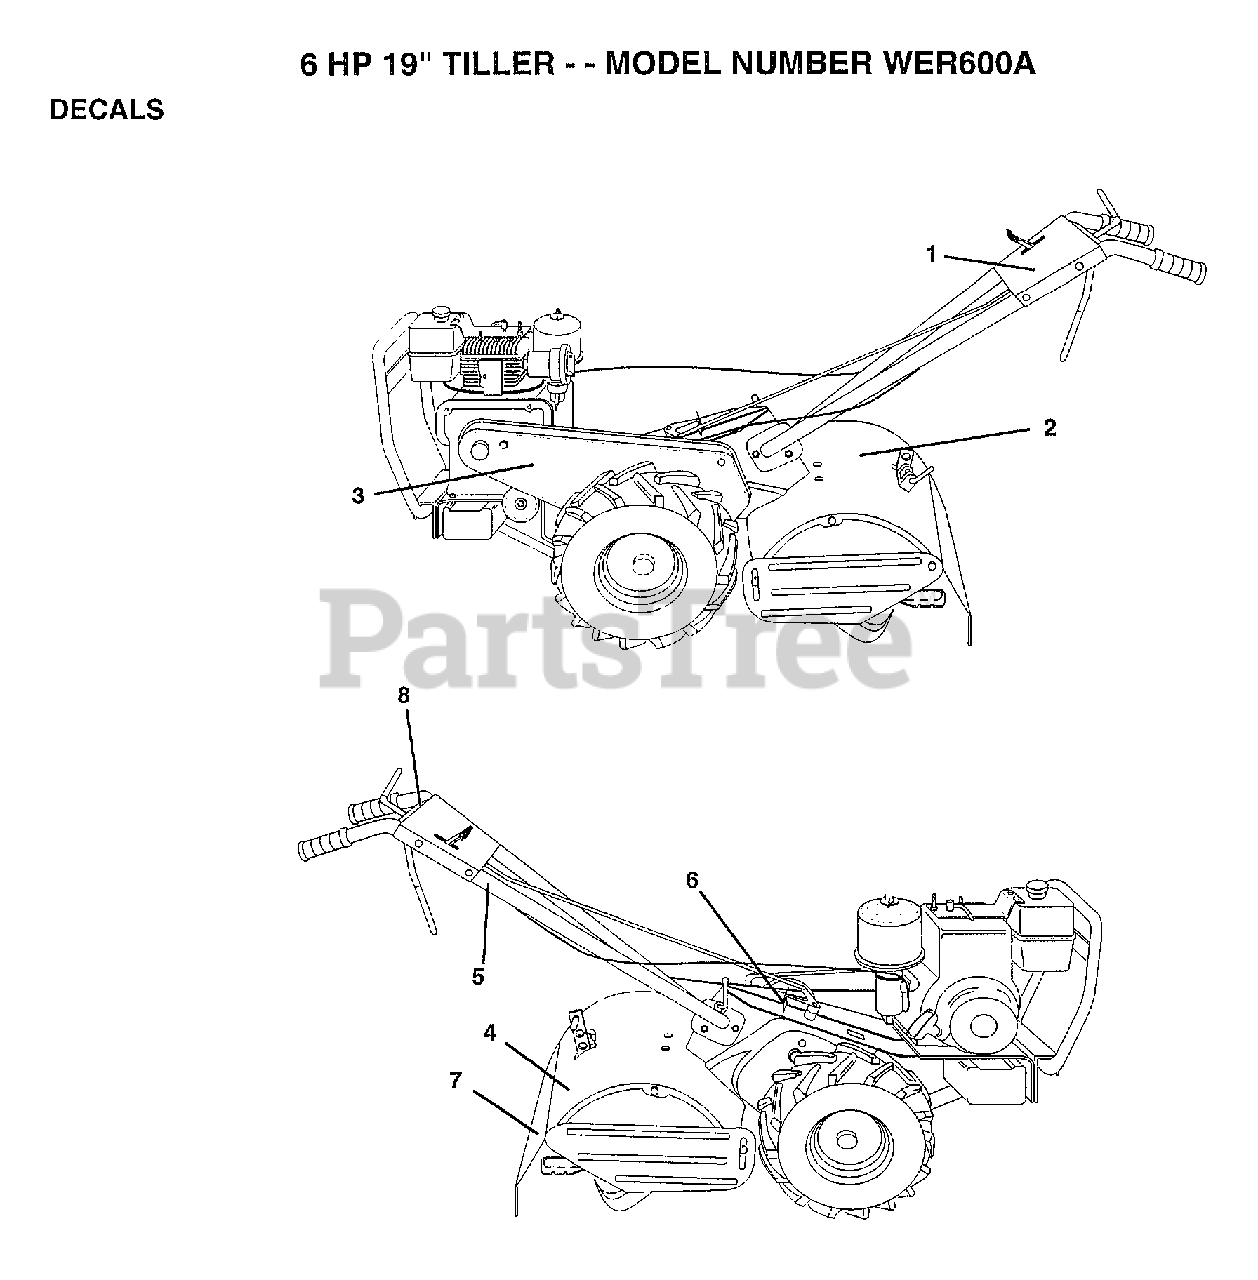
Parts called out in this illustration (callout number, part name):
1	DECAL.PNL.SERV.19
2	DECAL.TIL.SERV.19
3	DECAL BELT GUARD
4	DECAL.CAUTION.E/S
5	DECAL.HAND.PLACE
6	DECAL.SHIFT.IND.
7	DECAL.WARN.ROT.TI
8	DECAL.CONTROL
